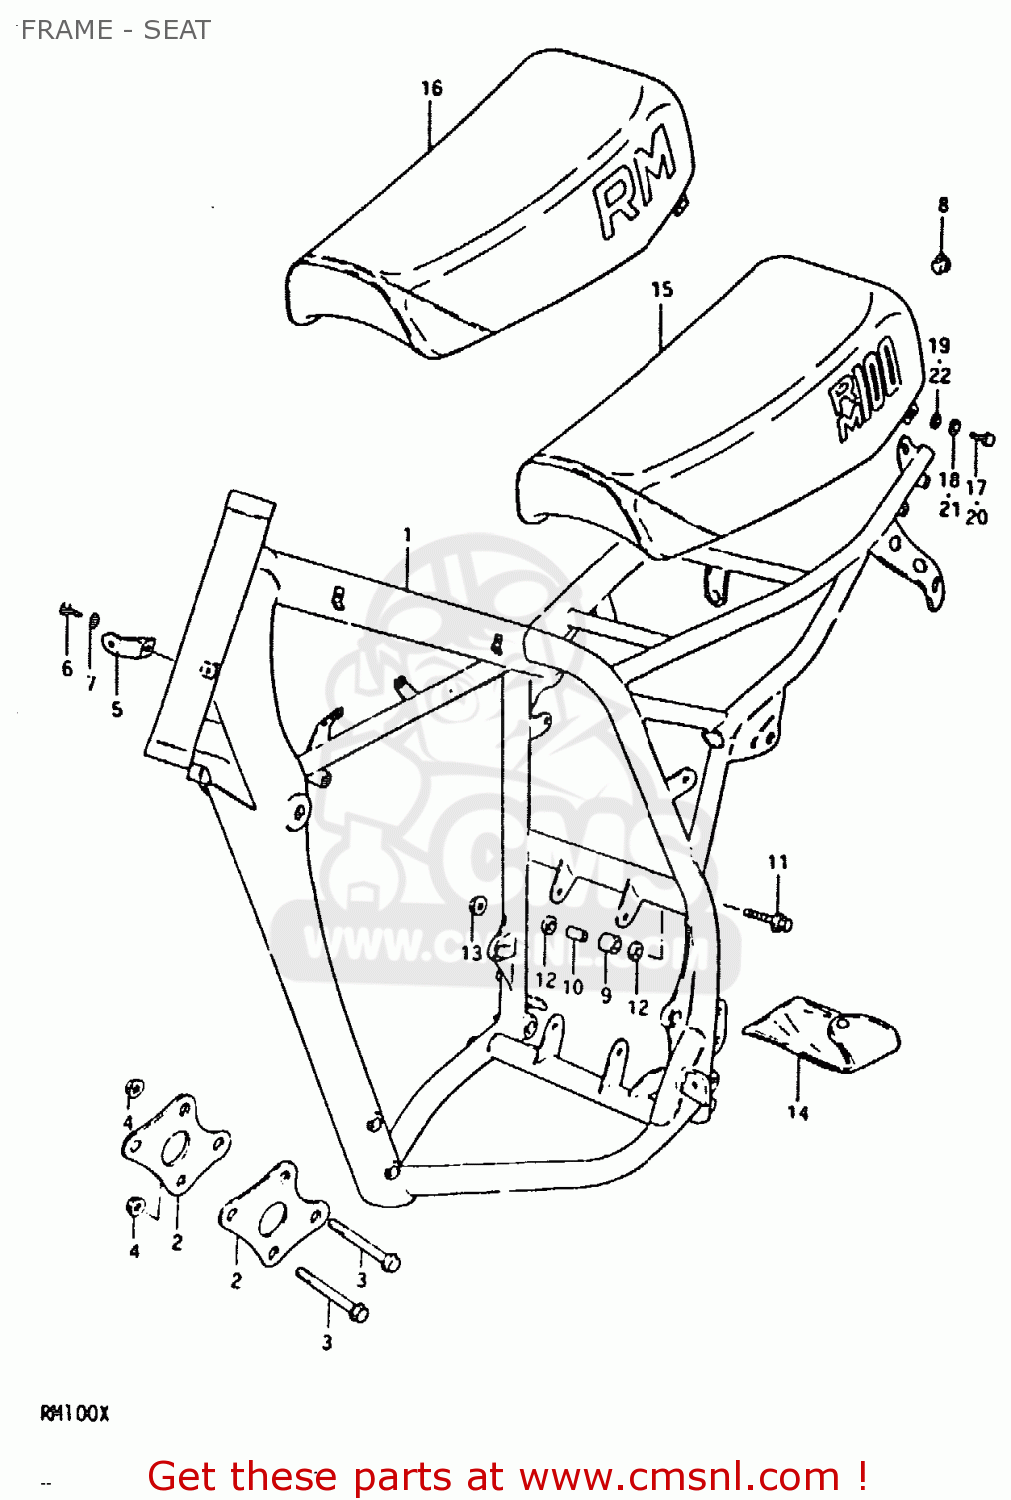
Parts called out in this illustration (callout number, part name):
1	FRAME
2	PLATE,ENGINE MOUNTING
3	BOLT(8X67)
4	NUT
5	PLATE,ENGINE MOUNTING
6	BOLT
7	LOCK WASHER
8	PLUG(OD:19)
9	ROLLER,CHAIN CONTROL
10	SPACER,CHAIN LENGTH ROLLER
11	BOLT(8X45)
12	WASHER
13	NUT
14	TOOL SET
15	SEAT ASSEMBLY
16	SEAT ASSEMBLY
17	BOLT, UPPER
18	LOCK WASHER
19	WASHER(6.5X18X1)
20	BOLT
21	LOCK WASHER
22	WASHER
